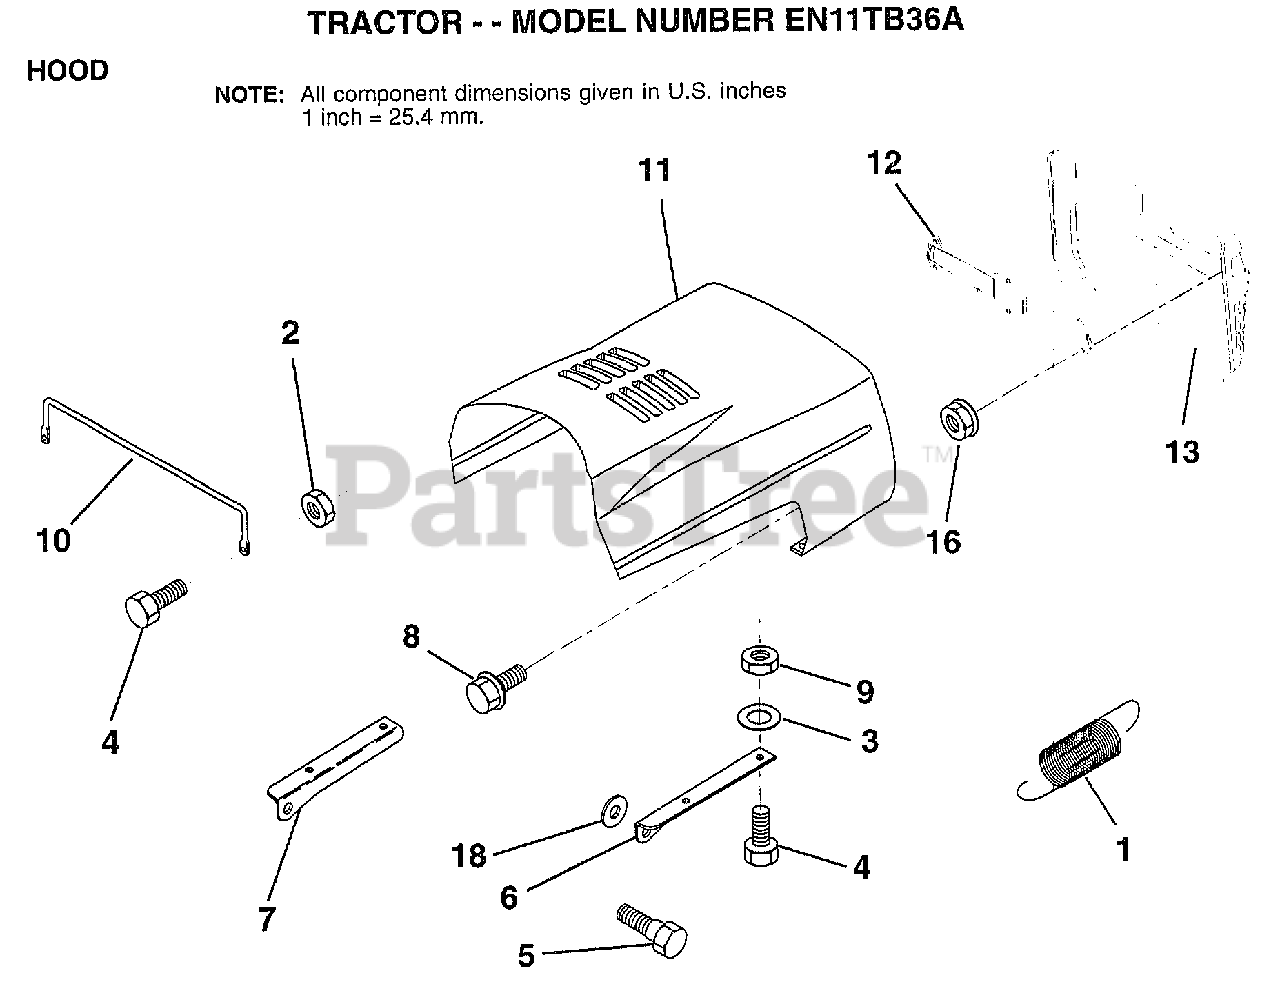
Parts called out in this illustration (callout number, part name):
1	EXT SPRING
2	NUT
3	WASHER
5	BOLT.SHLD.5/16-18
6	BRKT HOOD RH
7	BRKT HOOD LH
8	"SCREW,HWHD.HI-LO#13-16X3/4"
9	NUT
10	"BRACE,HOOD"
13	GRILL (BLACK)
16	NUT
18	WASHER
